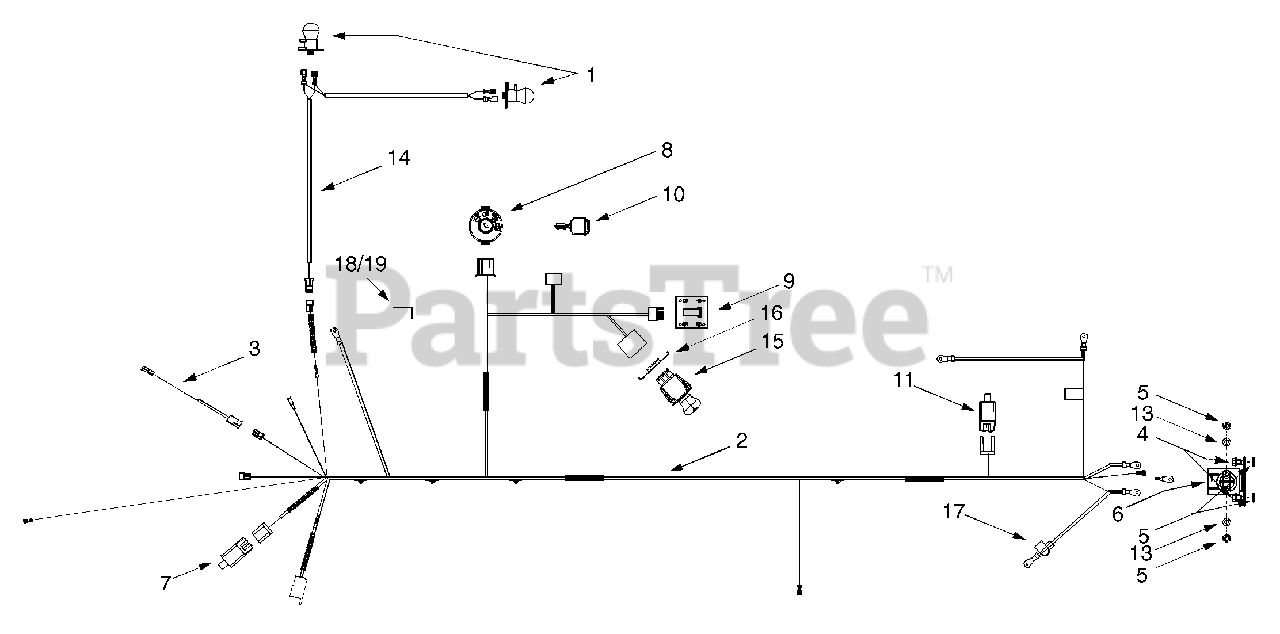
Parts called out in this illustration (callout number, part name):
1	Bulb/Socket Headlight Assembly
2	Wiring Harness w/o Ref. 14
3	Harness Adapter, #18 x 5
4	Self Tapping Screw, 1/4-20 x .5
5	Hex Nut, 1/4-20
6	Solenoid, 12-volt, 100 Amp
7	Snap Mount Safety Interlock Switch
8	Ignition Switch
9	Indicator Monitor / Hour Meter
10	Ignition Key
11	Safety Plunger Switch
13	Lock Washer, 1/4
14	Headlight Harness
15	Electric PTO Switch
16	Retainer Bracket
17	Positive Terminal Cover
19	20-amp Fuse
